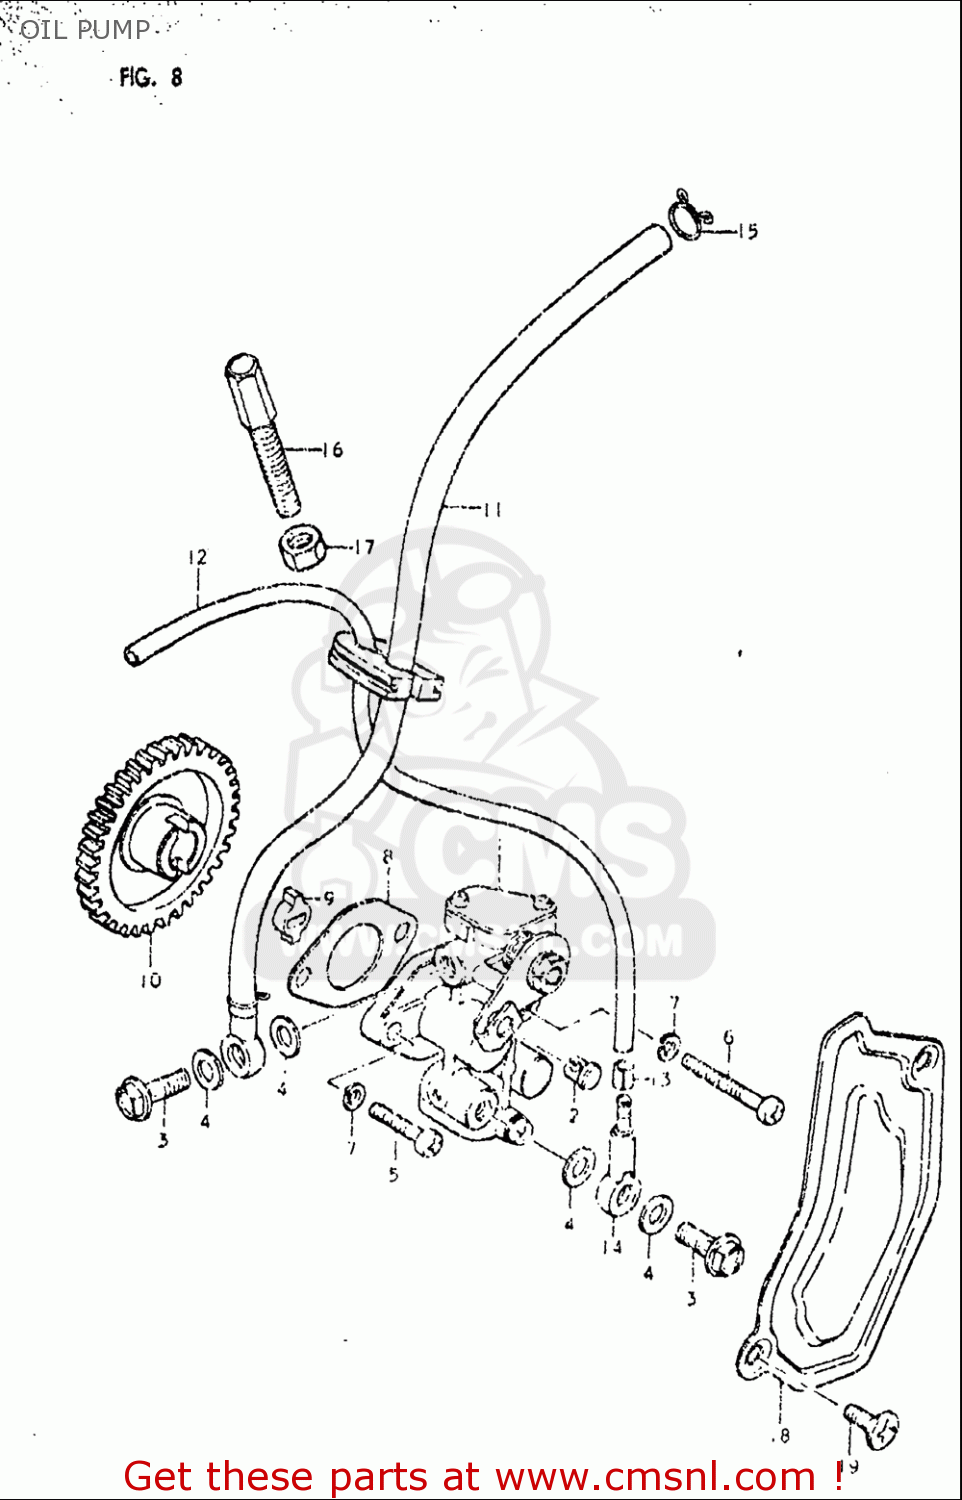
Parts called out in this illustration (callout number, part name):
1	PUMP ASSY,OIL
2	TERMINAL,CABLE
3	UNION BOLT
4	GASKET(6.2X11X1).2 (NAS)
5	SCREW
6	SCREW
7	WASHER,LOCK
8	GASKET,OIL PUMP (NAS)
9	PIECE,OIL PUMP DRIVE
10	GEAR,OIL PUMP DRIVE
11	HOSE,INLET
12	HOSE,NO.2
13	CLIP
14	VALVE,CHECK
15	CLIP
16	BOLT
17	NUT
18	CAP,OIL PUMP INSPECTION
19	SCREW
